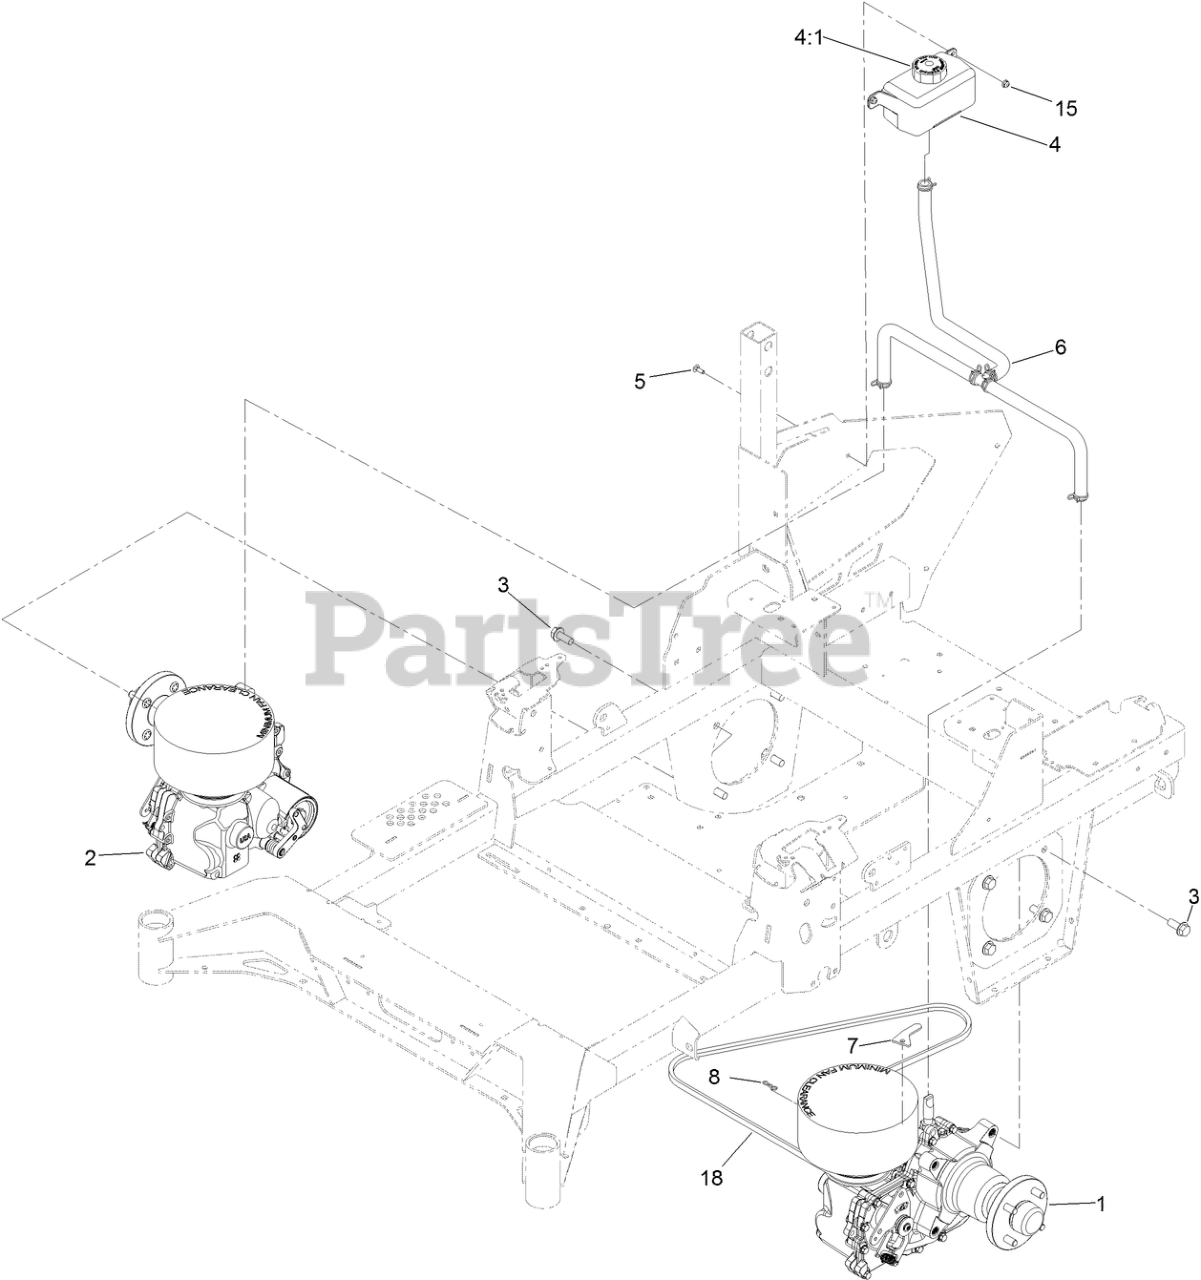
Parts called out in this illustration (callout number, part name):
1	LH TRANSAXLE ASM
2	RH TRANSAXLE ASM
3	SCREW-HHF
4	HYDRAULIC RESERVOIR ASM
4:1	CAP-RESERVOIR, HYD
5	SCREW-CARR
6	ASM-HOSE, HYDRAULIC
7	PLATE-LEVER, BYPASS
8	PIN-COTTER, LOCKING
15	NUT-HF
18	BELT-V
